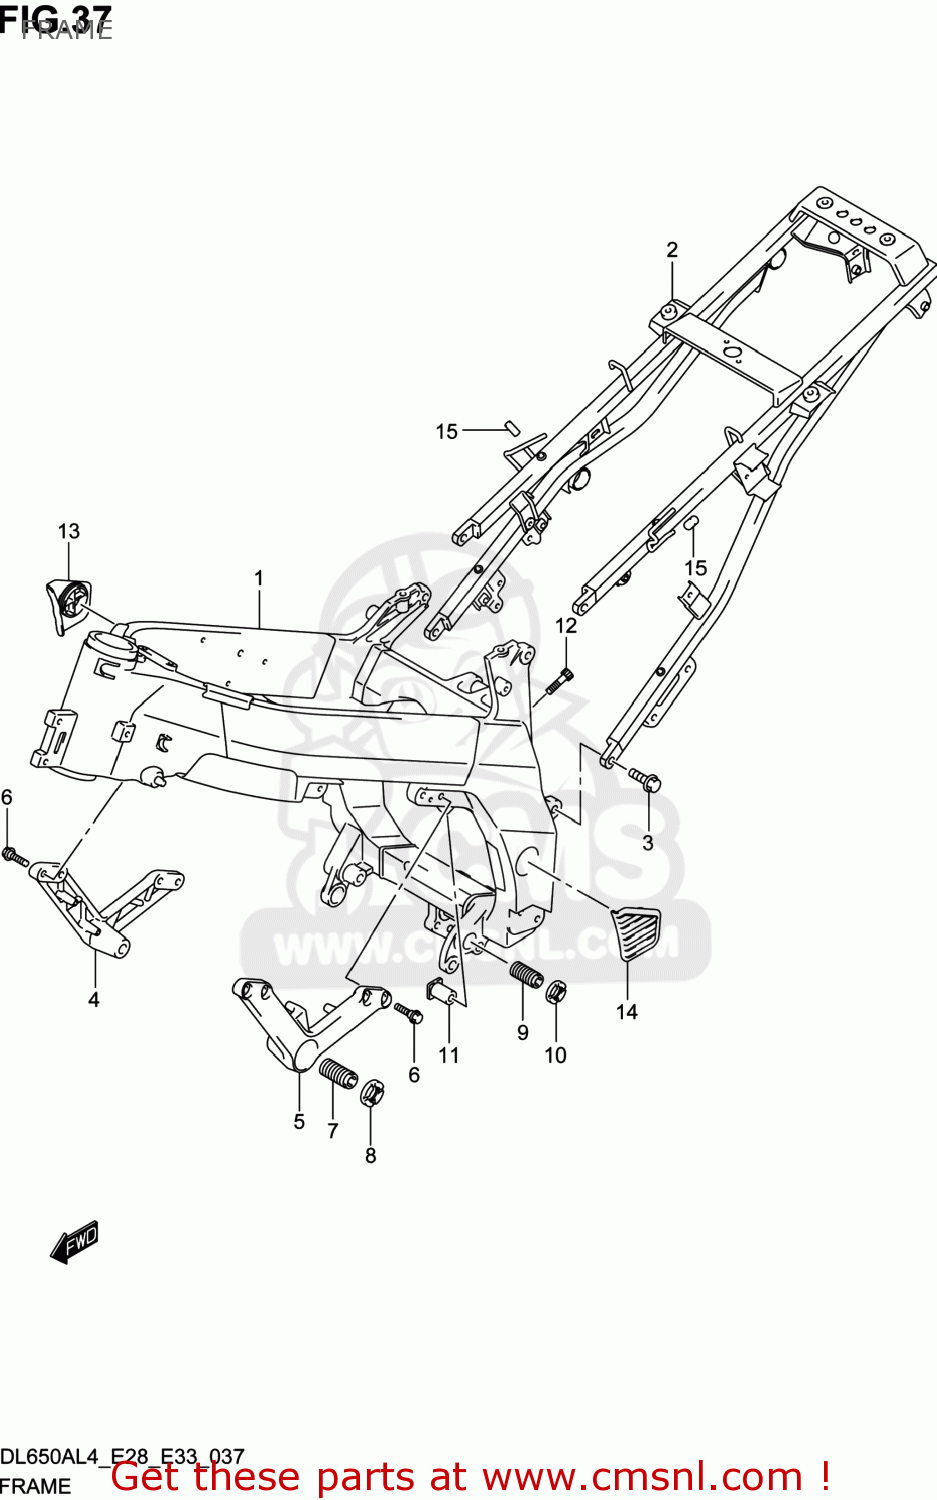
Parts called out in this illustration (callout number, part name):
1	FRAME(BLACK)
2	RAIL,SEAT
3	BOLT(10X30)
4	BRACKET,ENGINE MOUNTING,R
5	BRACKET,ENGINE MOUNTING,L
6	BOLT(8X30)
7	BOLT,CRANK CASE ADJUST CTR
8	NUT,CRANK CASE ADJUST CTR
9	BOLT,CASE LWR & RR HEAD ADJ
10	NUT,CRANK CASE ADJUST LWR
11	SPACER,MOUNTING RR UPR,R
12	BOLT(8X38)
13	COVER,PIVOT,R
14	COVER,PIVOT,L
15	CAP
